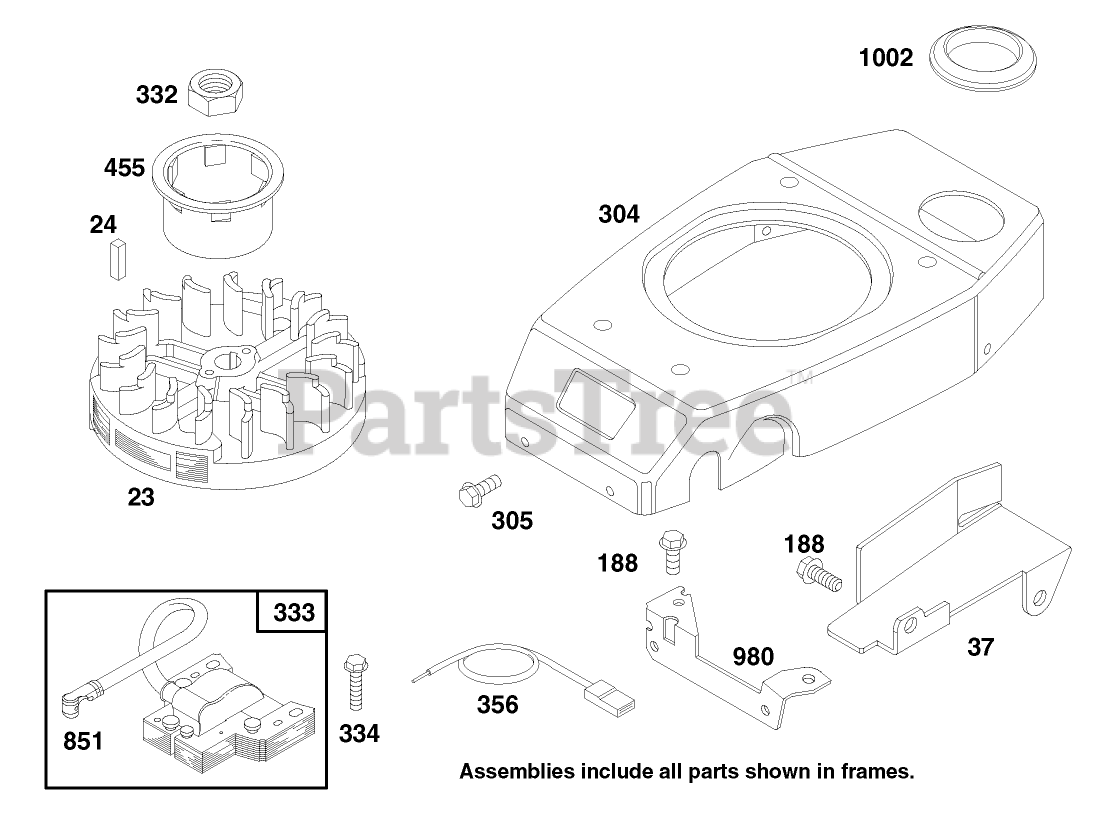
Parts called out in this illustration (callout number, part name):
24	KEY - FLYWHEEL
37	GUARD - FLYWHEEL
304	HOUSING - BLOWER
305	SCREW - HEX HEAD
332	NUT - HEXAGON
356	WIRE - GROUND
980	BRACKET-BLOWER HSG
